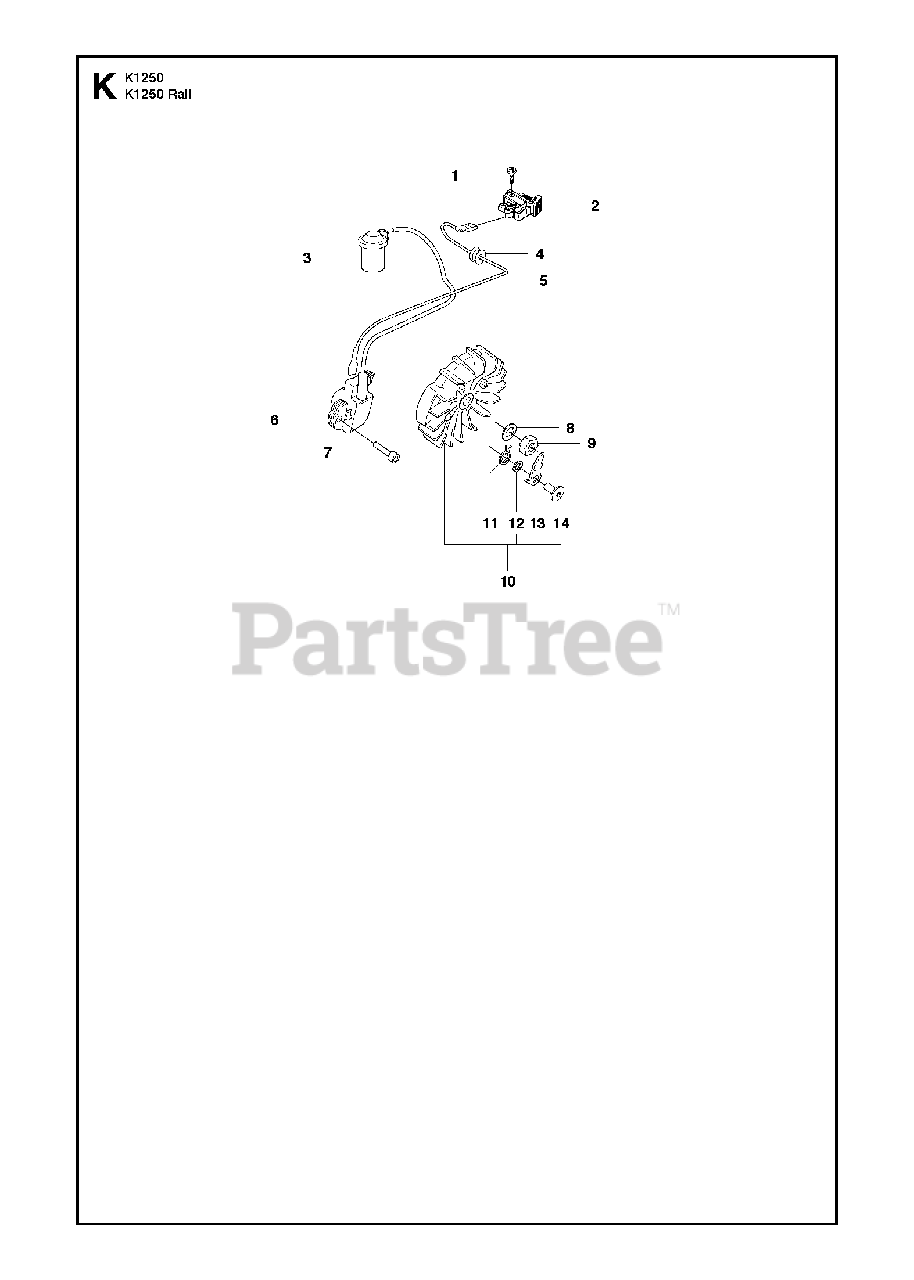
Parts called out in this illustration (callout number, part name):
1	SCREW CCRPANM
2	STOP SWITCH
3	SPARK PLUG CAP
4	CABLE GROMMET
6	IGNITION SYSTEM
8	SPRING WASHER
10	FLYWHEEL ASSYIncl. 11 - 14
